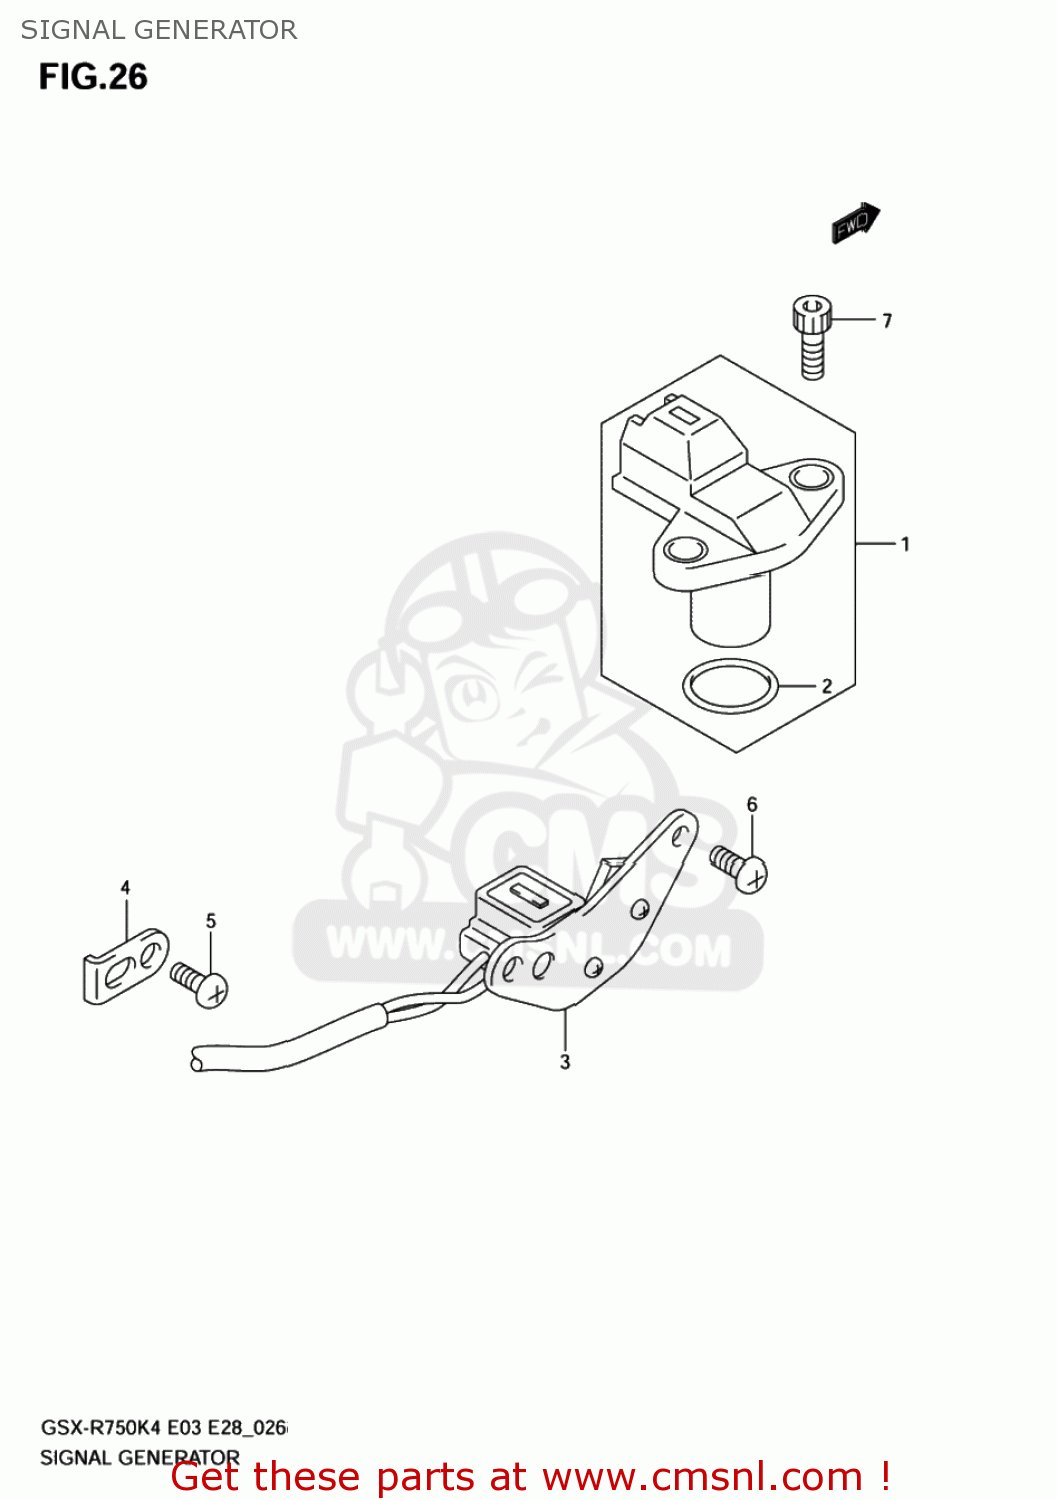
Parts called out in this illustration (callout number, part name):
1	SENSOR ASSY,CAM POSITION
2	PACKING (NAS)
3	STARTER SIGNAL GENERATOR
4	CLAMP,SIGNAL GENERATORERATOR
5	SCREW
6	SCREW
7	BOLT,OIL FILLE
